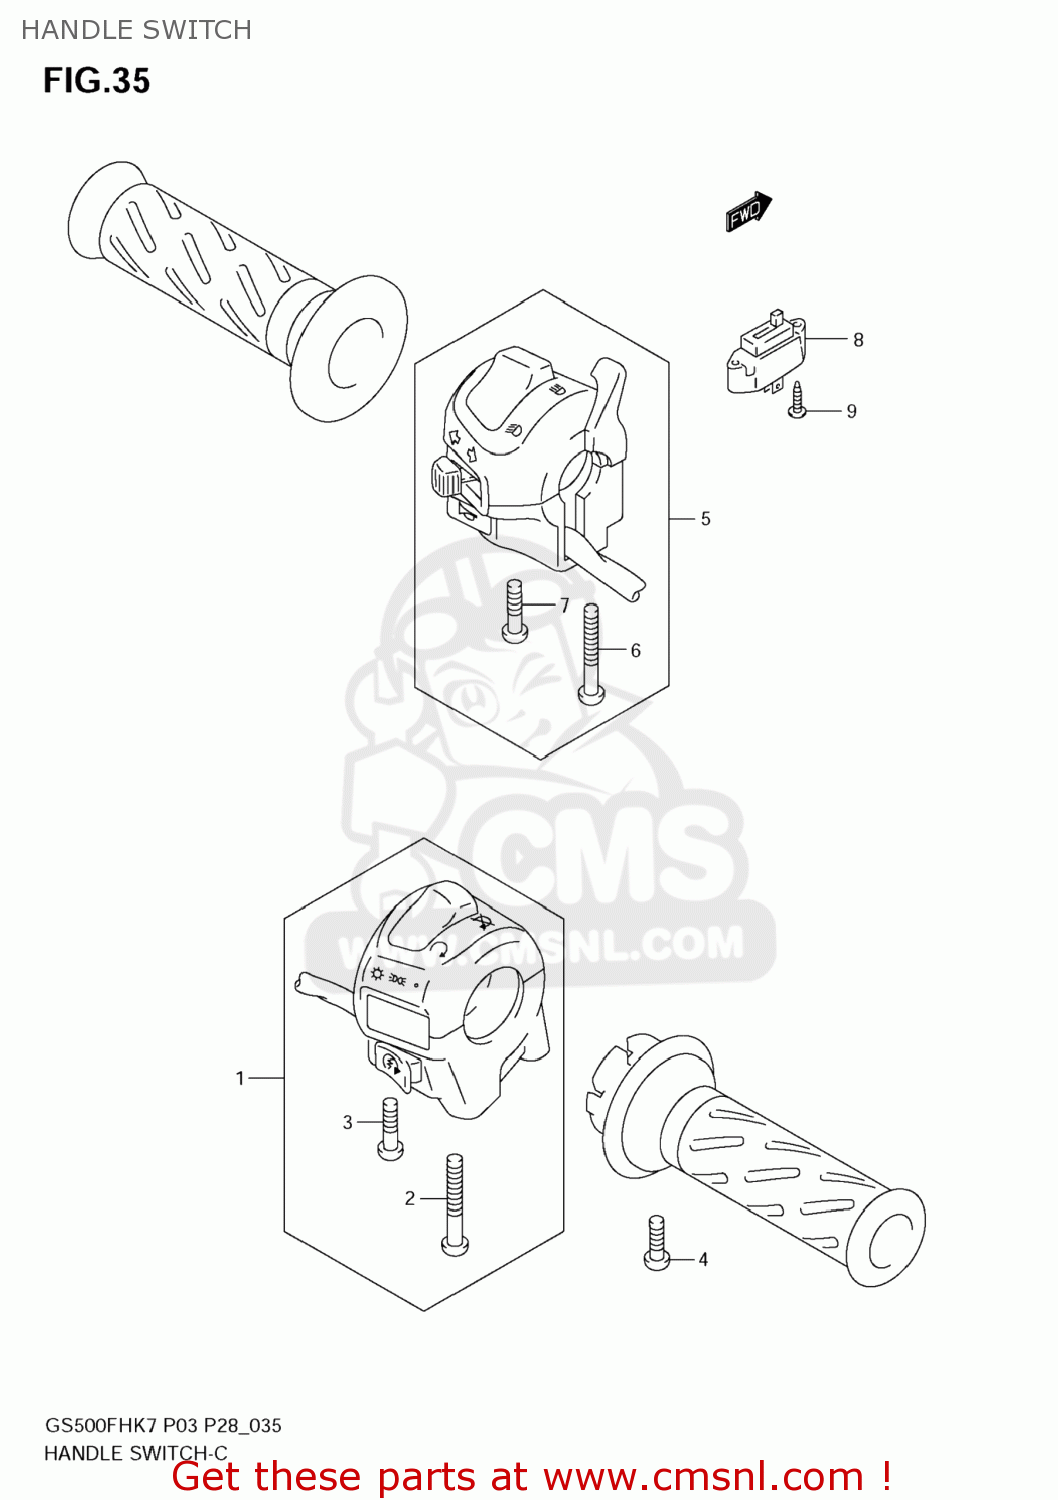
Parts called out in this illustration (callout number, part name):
1	SWITCH ASSY,HA
2	SCREW
3	SCREW
4	SCREW, THROTTLE CABLE
5	SWITCH ASSY,HANDLE,L
6	SCREW
7	SCREW(5X25)
8	SWITCH ASSY,CLUTCH
9	SCREW(3X14)
10	WASHER
